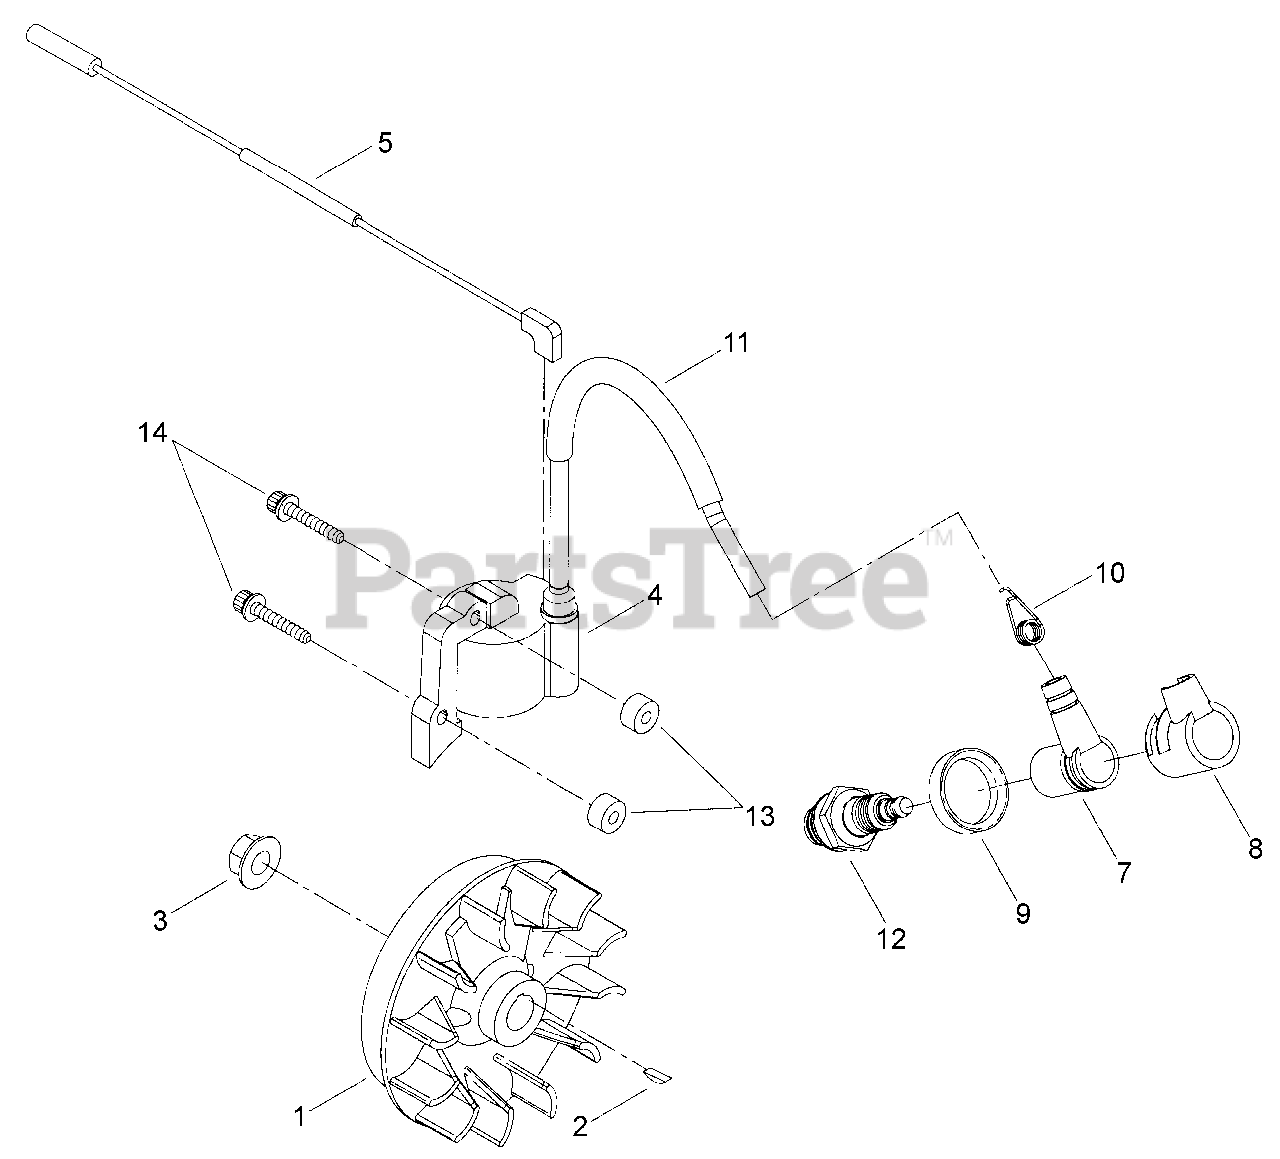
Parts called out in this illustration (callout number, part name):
1	FLYWHEEL
2	KEY, WOODRUFF 3×10
3	NUT M8
4	COIL, IGNITION
5	LEAD
7	CAP, SPARK PLUG
8	COVER, CAP
9	SEAL, SPARK PLUG
10	TERMINAL, SPARK PLUG
11	TUBE, IGNITION COIL
12	SPARK PLUG
13	INSULATOR 4.2×11×6
14	BOLT M4×26
